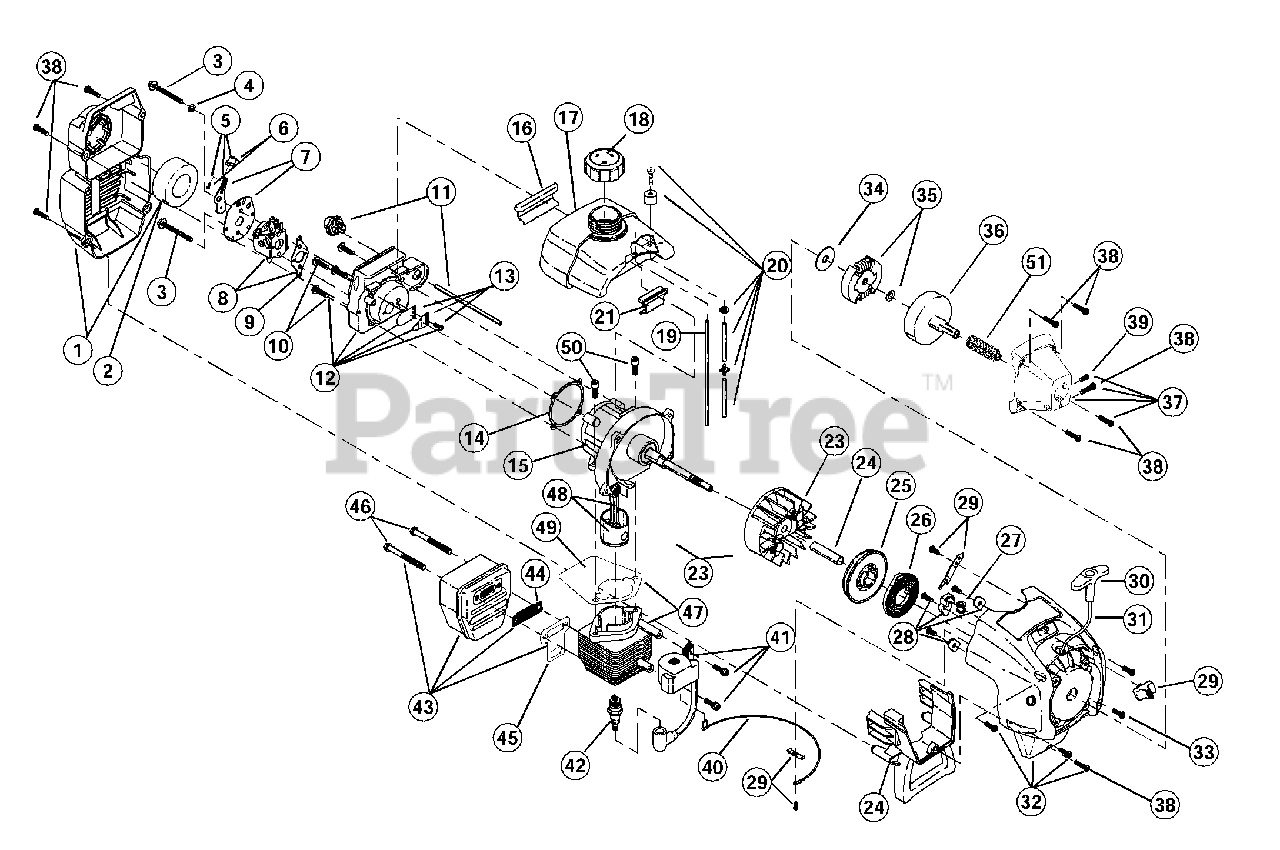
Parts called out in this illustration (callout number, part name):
1	Air Cleaner/Muffler Cover Assembly
2	Air Cleaner Filter
3	Carburetor Mounting Screw Assembly
4	Wavey Washer
5	Choke Lever Assembly
6	Choke Knob and Screw
7	Choke Lever and Plate
8	Carburetor Assembly
9	Carburetor Gasket
10	Carb Mount Screw
11	Primer and Hose Assembly
12	Carb Mount Assembly
13	Reed Assembly
14	Carburetor Mount Gasket
15	Crank Case Service Assembly
16	Rear Mounting Pad
17	Fuel Tank Assembly
18	Fuel Cap Assembly
19	Fuel Return Line
20	Fuel Line Assembly
21	Front Mounting Pad
22	Shroud Extension and Stand
23	Flywheel Assembly
25	Recoil Pulley Assembly
26	Recoil Spring
27	Rope Guide
28	Pulley Retainer Assembly
29	Switch Assembly
30	Pull Handle
32	Starter Housing Assembly
33	Housing Screw
34	Clutch Washer
35	Clutch Rotor Assembly
36	Clutch Drum Assembly
37	Clutch Cover Assembly
39	Anti-Rotation Screw
40	Wire Lead
41	Module Assembly
42	Spark Plug
43	Muffler Assembly
44	Spark Arrestor Screen
45	Exhaust Gasket
46	Muffler Mounting Bolt Assembly
47	Cylinder Assembly
48	Piston and Rod Assembly
49	Cylinder Gasket
50	Cylinder Bolt
